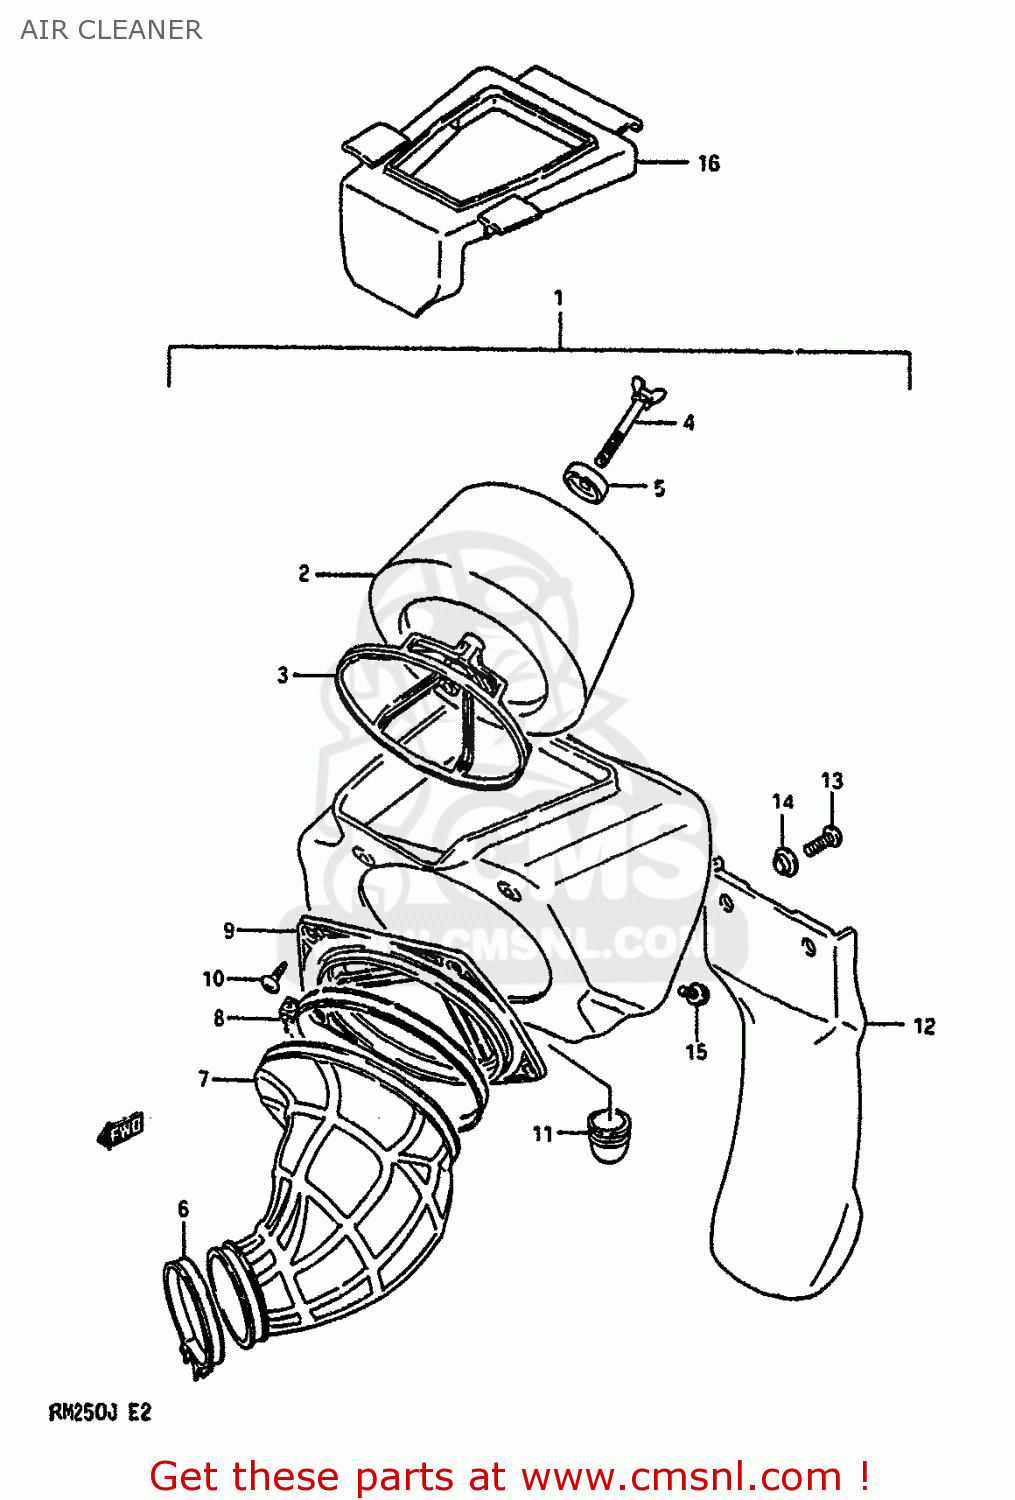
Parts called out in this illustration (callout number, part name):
1	CLEANER ASSEMBLY,AIR (ASB)
2	FILTER,AIR CLEANER
3	HOLDER,FILTER
4	BOLT,WING
5	WASHER,AIR CLEANER
6	CLAMP
7	TUBE,AIR CLEANER OUTLET
8	CLAMP
9	HOLDER,FILTER
10	SCREW
11	TUBE,DRAIN
12	GUARD,MUD
13	SCREW
14	COLLAR
15	BOLT
16	MUD GUARD,B
